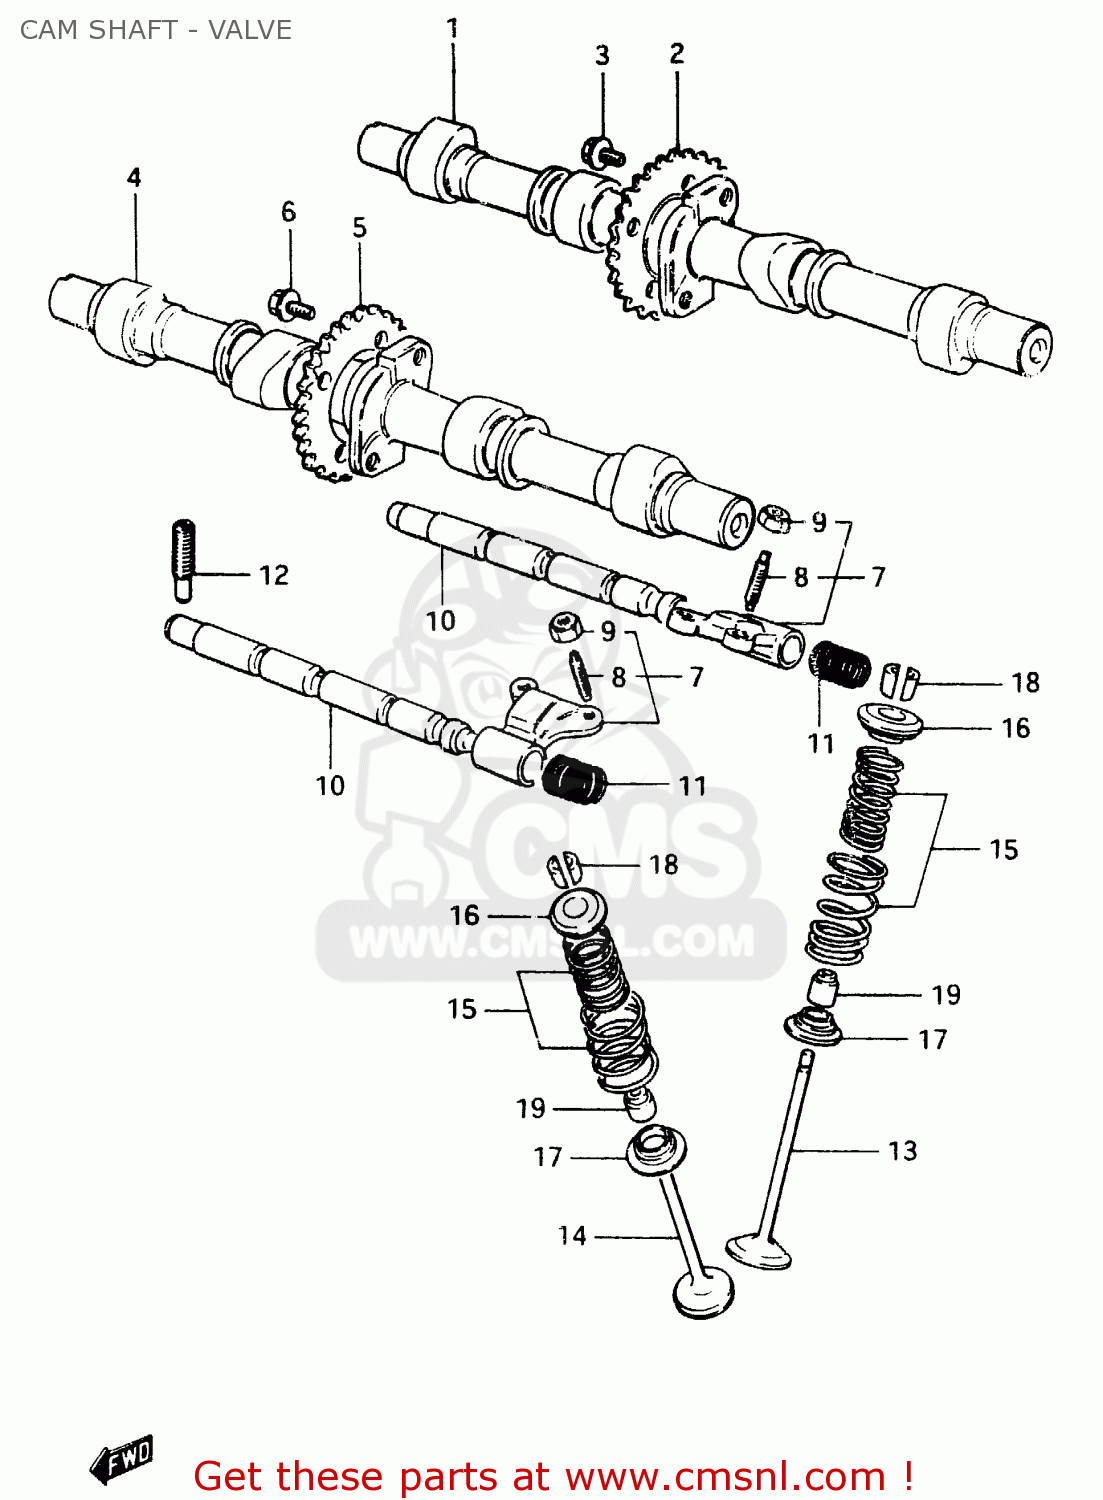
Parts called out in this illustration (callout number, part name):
1	CAM SHAFT, INTAKE
2	SPROCKET, EXHAUST CAM SHAFT
3	BOLT(7X11)
4	CAM SHAFT, EXHAUST
5	SPROCKET, EXHAUST CAM SHAFT
6	BOLT(7X11)
7	ARM, VALVE ROCKER
8	SCREW,TAPPET ADJUSTING
9	NUT,ADJUSTING
10	SHAFT, VALVE ROCKER ARM
11	SPRING
12	SCREW
13	VALVE,INTAKE
14	VALVE,EXHAUST
15	SPRING SET,VALVE
16	RETAINER,VALVE SPRING
17	SEAT,VALVE SPRING
18	COTTER VALVE
19	OIL SEAL
